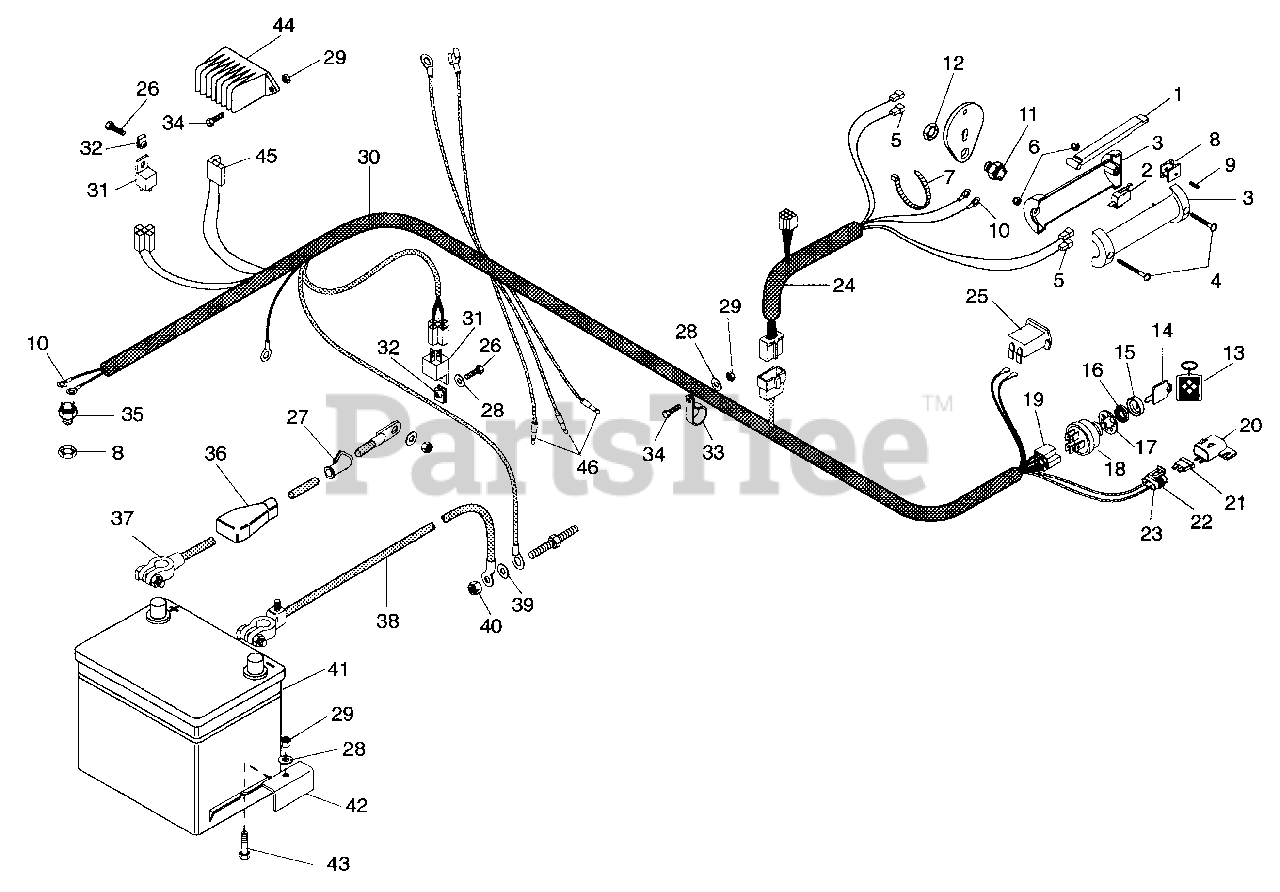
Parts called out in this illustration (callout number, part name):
1	Lever
2	Switch
3	Handle, Left Hand & Right Hand
4	Screw-Machine 10-24 x 1.50
5	Terminal, Female
6	Nut-Locking 10-24
7	Tie Wrap, Black
8	Holder Switch
9	Pin-Roll .094 x .750
10	Terminal, Eyelet
11	Switch, Interlock Closed
12	Nut-Stamped .56-18
13	Key Chain
14	Ignition Switch Key
15	Cap-Ignition Switch
16	Nut-Panel .562-24 Greco
17	Washer-Lock Internal .563 x .040
18	Ignition Switch
19	Connector
20	Cover
21	Fuse, 7.5 Amp
22	Terminal For 10-12 GA Wire
23	Assembly, Connector Weather Tight
24	Harness, Wiring Handlebar
25	Hour Meter
26	Bolt-Hex .25-20 x .63
27	Boot, Insulator
28	Washer-Flat-Steel .281 x .620 x .065
29	Nut-Locking-Nylon .250-20
30	Harness, 10-HP Elect Kawasaki
31	Relay
32	Nut-Speed .25-20
33	Clamp, Cushioned Steel
34	Bolt-Hex .25-20 x .75 Grade 5
35	Switch, Interlock Open
36	Cover, Battery Terminal
37	Cable, Battery to Magneto Switch
38	Cable, Negative Battery(12 & 16)
39	Washer-Flat-Steel .406 x .812 x .065
40	Nut-Locking-Nylon .375-16
41	Battery, 12 V
42	Clamp
43	Bolt-Round Head Square Neck .25-20 x 1.75
44	Reg, Rectifier
45	Connector
46	Terminal, Male
